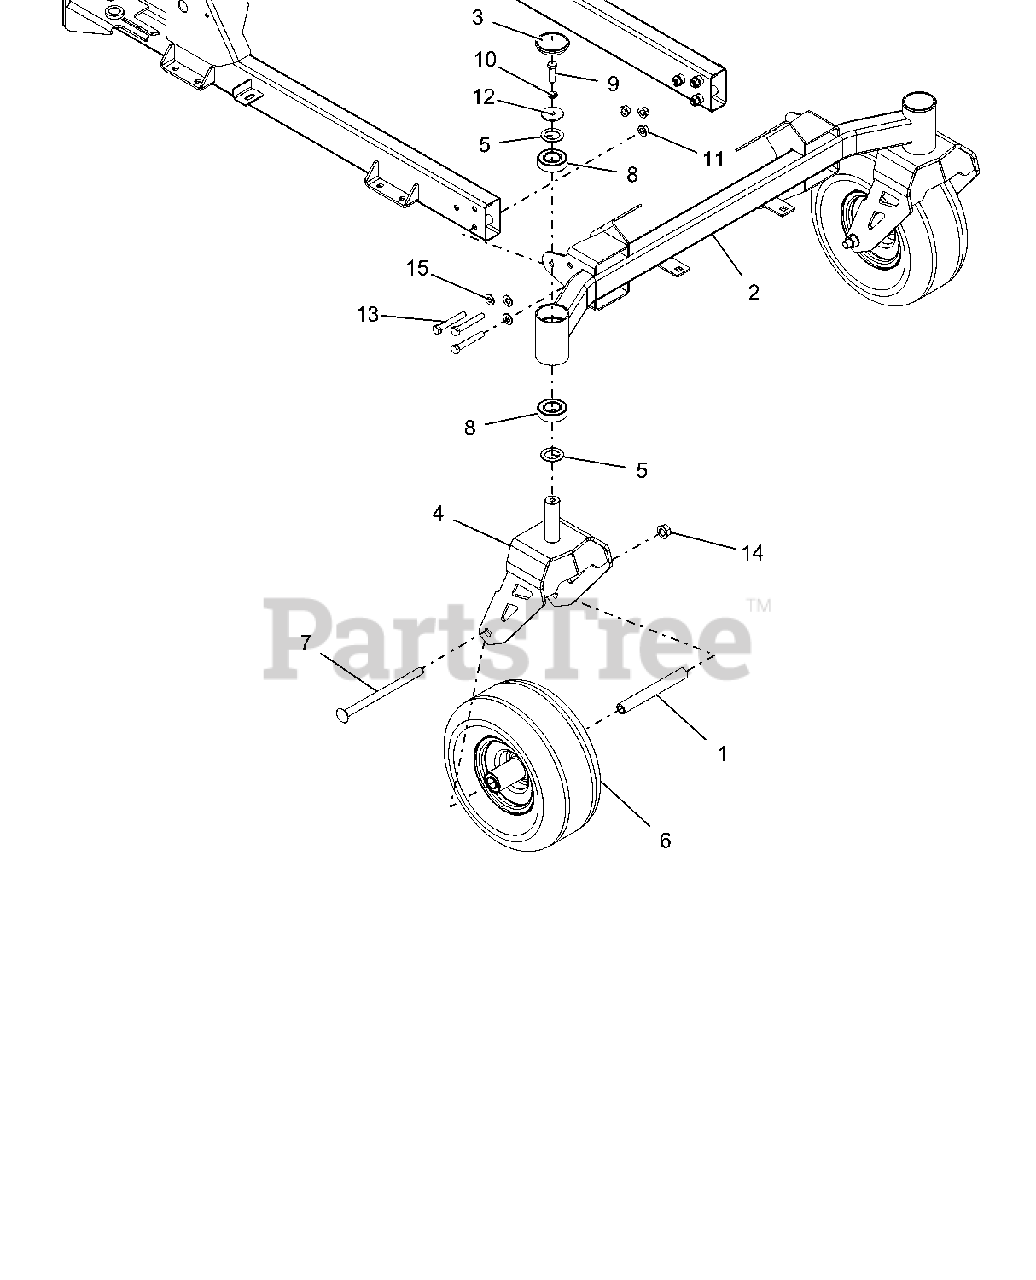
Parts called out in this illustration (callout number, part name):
1	SPACER, FRONT WHEEL (WIDE 6.0)
2	WLDMT, AXLE FRONT
3	CAP, DUST
4	WLDMT, CASTER FORK (WIDE)
5	WSHR-HRD-THRS 1.007X1.542X.062
6	TIRE/WHEEL ASSY, 11X6-5
7	@BLT-RDHDSQNK .50-13X7.50 G5YZ
8	BRG,BALL 1.00X2.00X.563(1641)
9	@BLT-HEX .38-16X1.25 GR5 YWZC
10	@WSHR-LK .38X.094 REG YWZC
11	NUT-LK-TOP-FLG .38-16 GRG YWZC
12	WSHR-FL-STL .380X1.50X.125YWZC
13	BLT-HEX .38-16X2.50 GR8 YWZC
14	@NUT-LK-TOP-FLG .50-13 YWZC
15	WSHR-HDND .406X.812X.055
